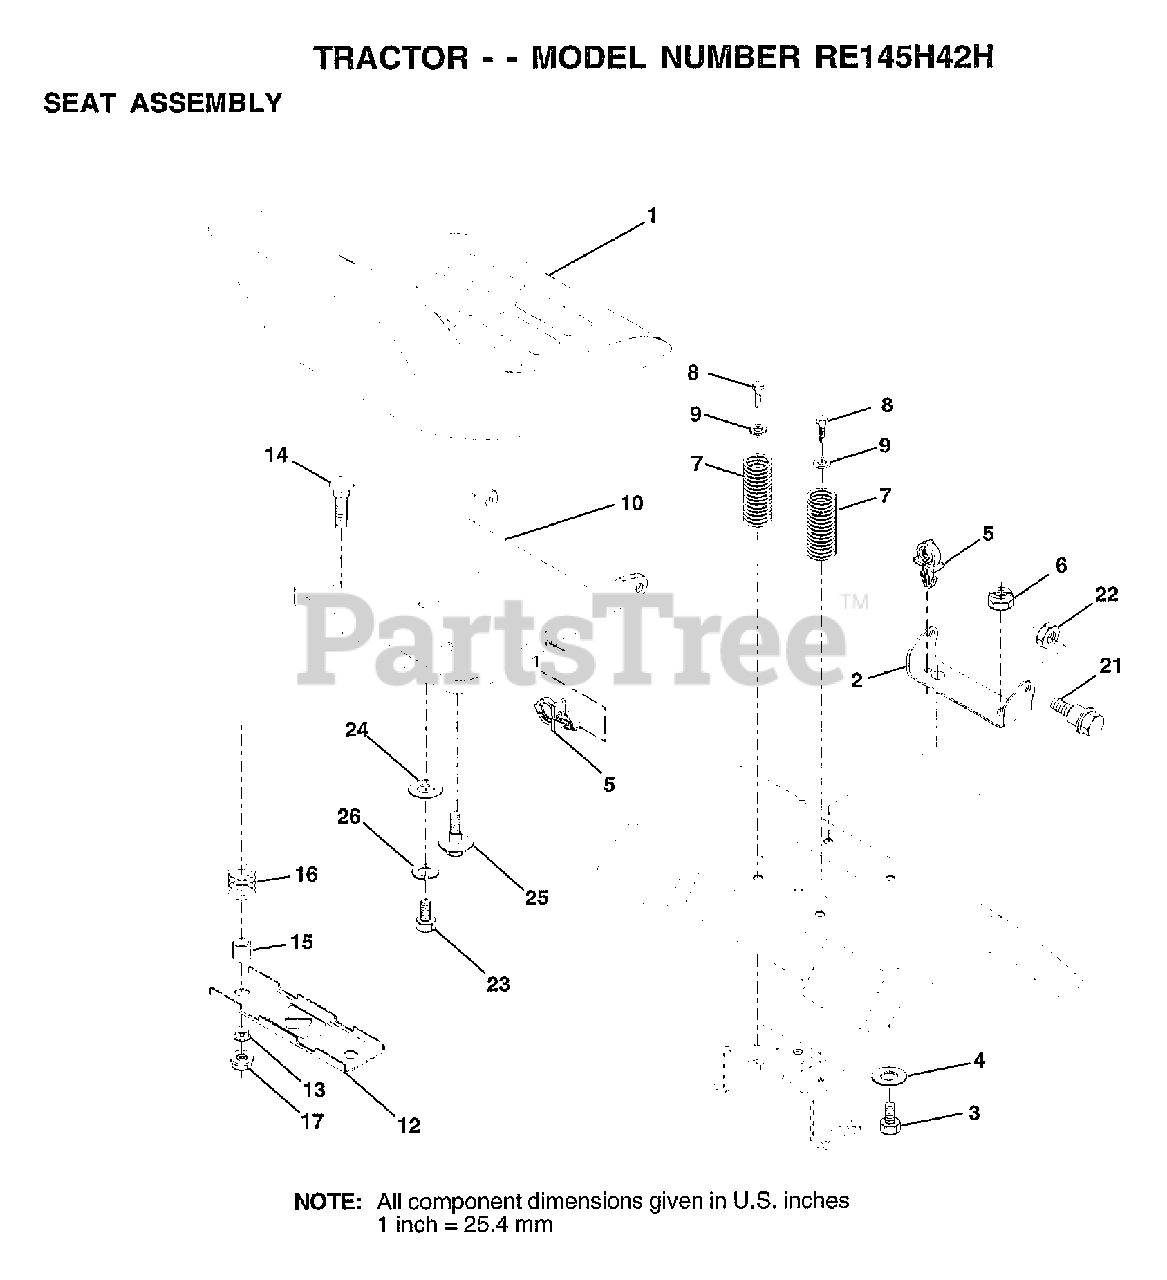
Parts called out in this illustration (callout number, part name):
2	BRACKET PVT SEAT
3	BOLT
4	WASHER PM
5	CLIP.PUSH-IN.HING
6	NUT
7	SPRING COMPRESSIO
8	SCREW
9	WASHER
10	PAN-SEAT
12	BRKT SWITCH
13	BUSHING
14	BOLT-RD HD SQ NK
15	SPLIT SPACER
16	SPRING
21	BOLT
22	NUT
23	BOLT HEX BLACK
24	WASHER
25	"BOLT,SHOULDER"
26	LOCKWASHER
